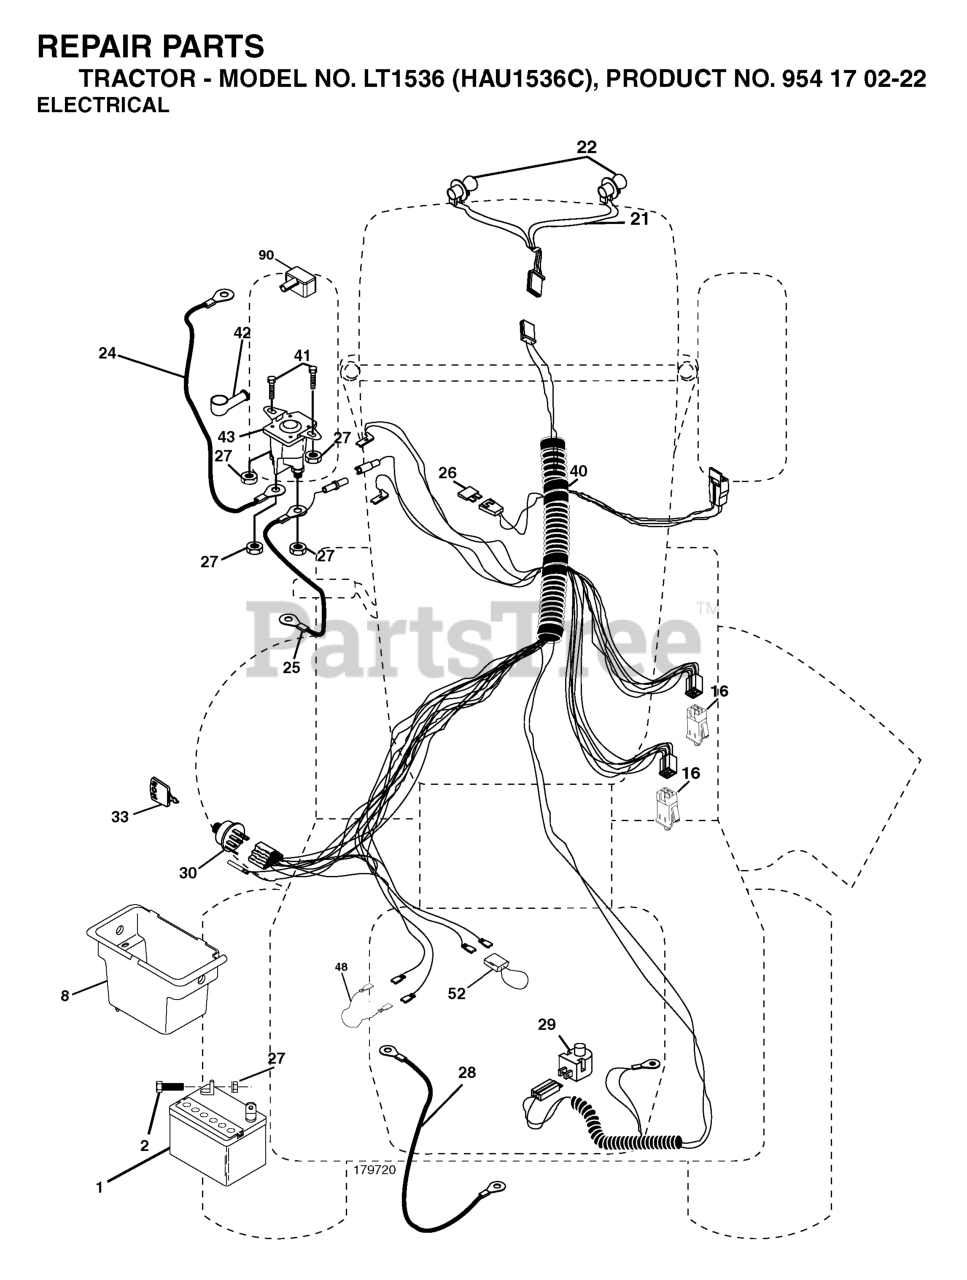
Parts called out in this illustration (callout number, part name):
1	BATTERY 12V .35 AMP
2	BOLT.HEX.1/4.X.3/4.DICHROMATE
8	BOX.BATTERY.FENDER
16	SWITCH INTERLOOK PUSH-IN
21	HARNESS.W/LIGHT SOCKET
24	BATTERY CABLE GT
25	CABLE BATTERY
26	FUSE 20AMP
27	NUT
28	CABLE T
29	RP.SWITCH.PLUNGER.NC.GRAY
30	IGNITION SWITCH
33	KEY MLD GEN DELTA
40	HARNESS.IGNITION
41	BOLT
42	TERMINAL COVER
43	SOLENOID
48	ADAPTER.AMMETER
52	WIRE PROTECTION LOOP
90	COVER TERMINAL
